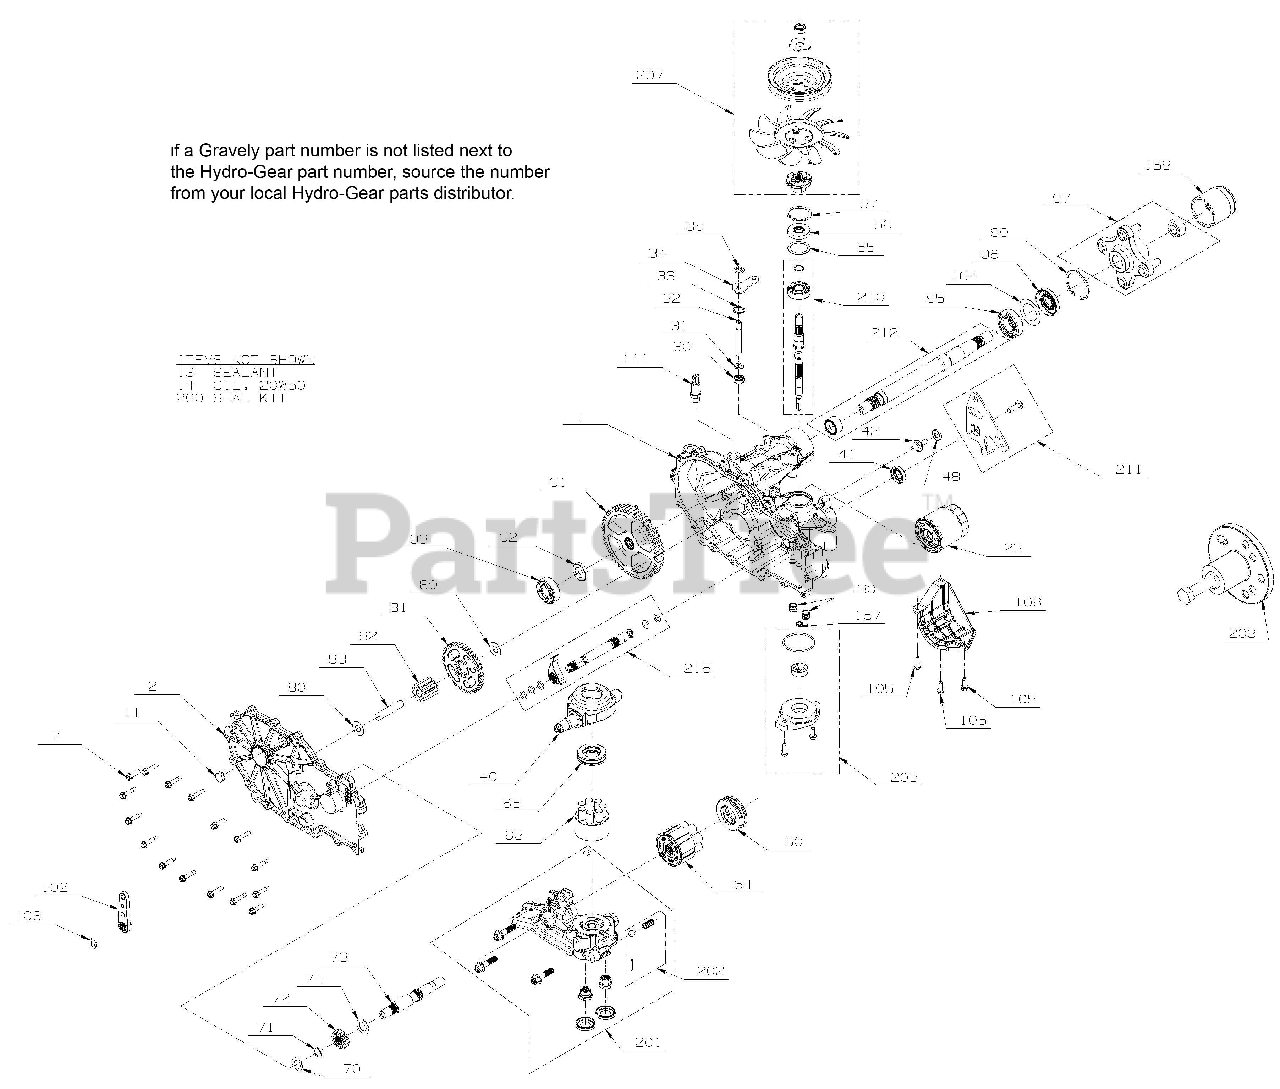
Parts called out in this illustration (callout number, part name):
1	KIT, MAIN HOUSING , CHARGE, CONTROL
2	KIT, SIDE COVER
7	SCREW,HEX WASHER 1/4-20X1.125
13	SEALANT TUBE 10.1OZ.
23	OIL FILTER, TRANSMISSION
30	SEAL, LIP .375X.75X.25
31	RING. RETAINING
33	RING, RET .750
34	ARM, BYPASS
35	RING, RTNG .
40	TRUNNION, SWASHPLATE
41	SEAL, LIP 18X32X7
42	STUD. SHORT 5/16-24
48	SPACER
55	WASHER 1.23X1.56X.04
56	SEAL, LIP 17X40X7
57	RING, RET 1.56 INT
60	HG THRUST BEARING (51462)
64	HG 16CC CYLINDER BLOCK (71579)
65	BEARING. THRUST 30 X 52 X 13
69	ASSY, BLOCK 7 PISTON
70	WASHER .63X1.0X.05
71	RING, RET 62 EXT
73	SHAFT, MOTOR
74	WASHER .71 X 1.16 X .04
80	WASHER .5X1.0X.032
83	JACK SHAFT (PIN)
90	RING, RETAINING
93	KIT, BEARING
95	BEARING, BALL 25.4 X 52 X 15
96	SEAL, LIP
97	KIT, HUB 4 BOLT
102	HANDLE, ACTUATING
105	HFHCS 1/4-20X.75
106	HG FILTER GUARD LH (52247)
111	KIT, FITTING 1/2 BEADED 9/16
130	TUBE, CHARGE TRIPLE O-RING
157	KIT, GEROTOR SEAL
158	CAP, AXLE
164	WASHER, 1.355 x 2.035 x .021 FLAT
200	KIT, SEAL
201	KIT, CENTER SECTION, CHARGE
202	KIT, CHARGE RELIEF
203	KIT, CHARGE
207	FAN PULLEY KIT 4.5X1.625
209	HUB PULLER 4 BLT HYDGEAR 71459
210	INPUT SHAFT 2800 HYDGEAR 71442
211	KIT, CONTROL ARM
212	KIT, SHAFT AXLE
215	KIT, INBOARD, RH ROT B / LH ROT A
